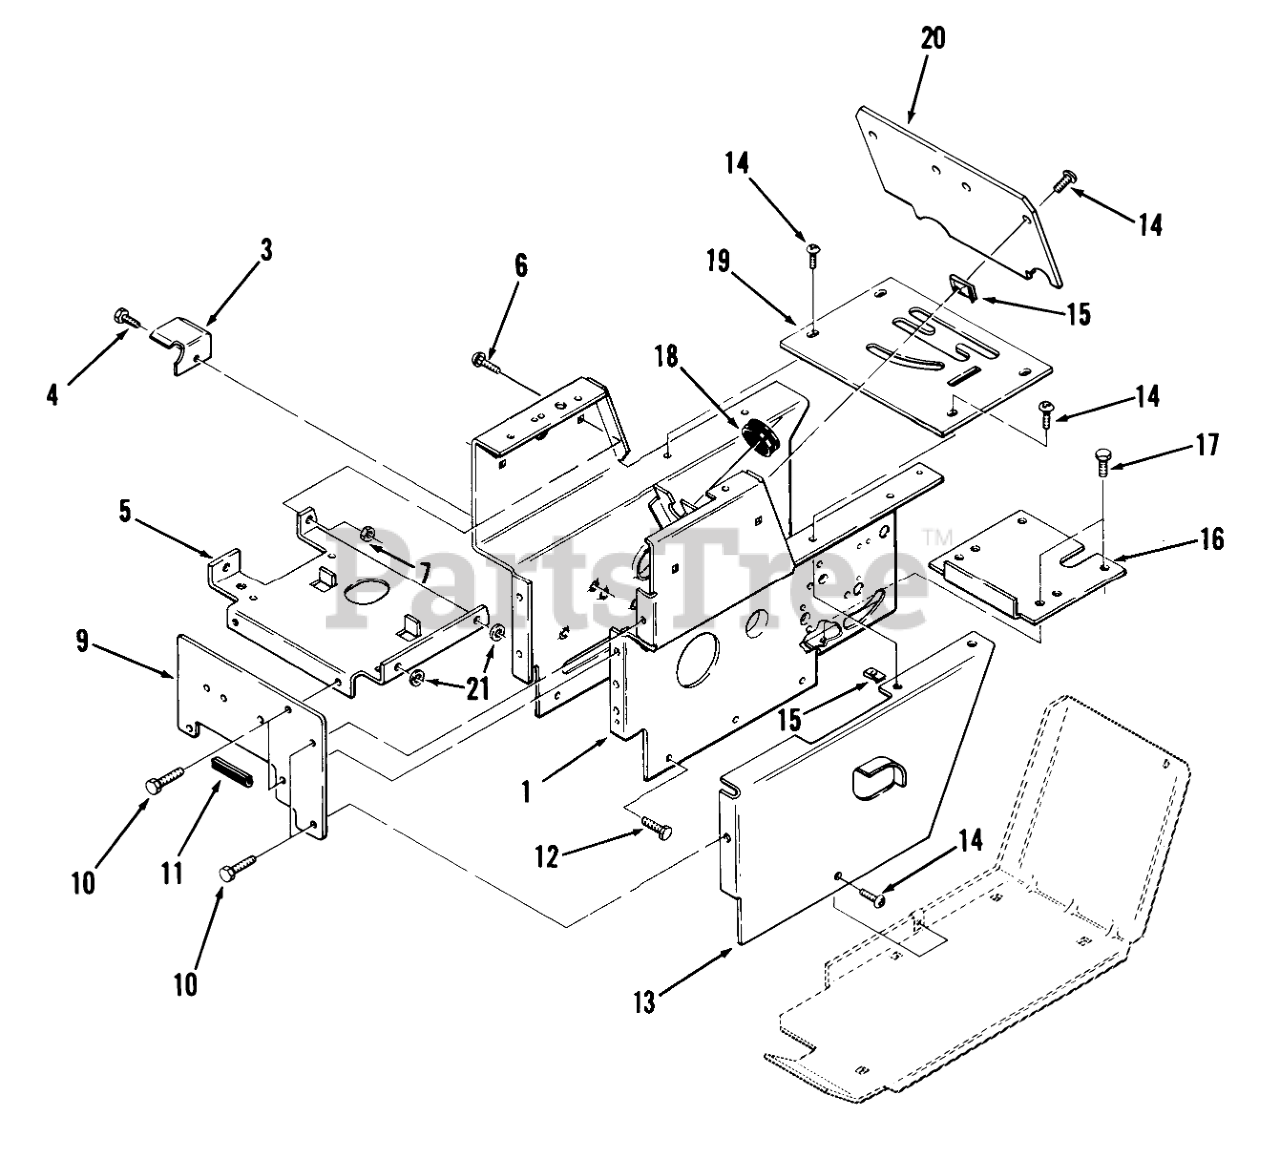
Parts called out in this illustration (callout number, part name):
1	Hoodstand
3	Belt Bracket
4	SCREW
5	Battery Support Bracket
6	CARRIAGE BOLT -4
7	Nut
9	Front Plate
10	SCREW
11	EDGE TRIM 2" 102896
12	SCREW
13	Side Cover LH
14	Screw
16	Cover-Dust
17	SCREW
18	GROMMET
19	Shift Cover Plate
19	Fuel Tank Support LH
20	PLATE-HOODSTAND REAR
20	Support-FueITank RH
21	WASHER 5/16 SAE
21	Bolt
